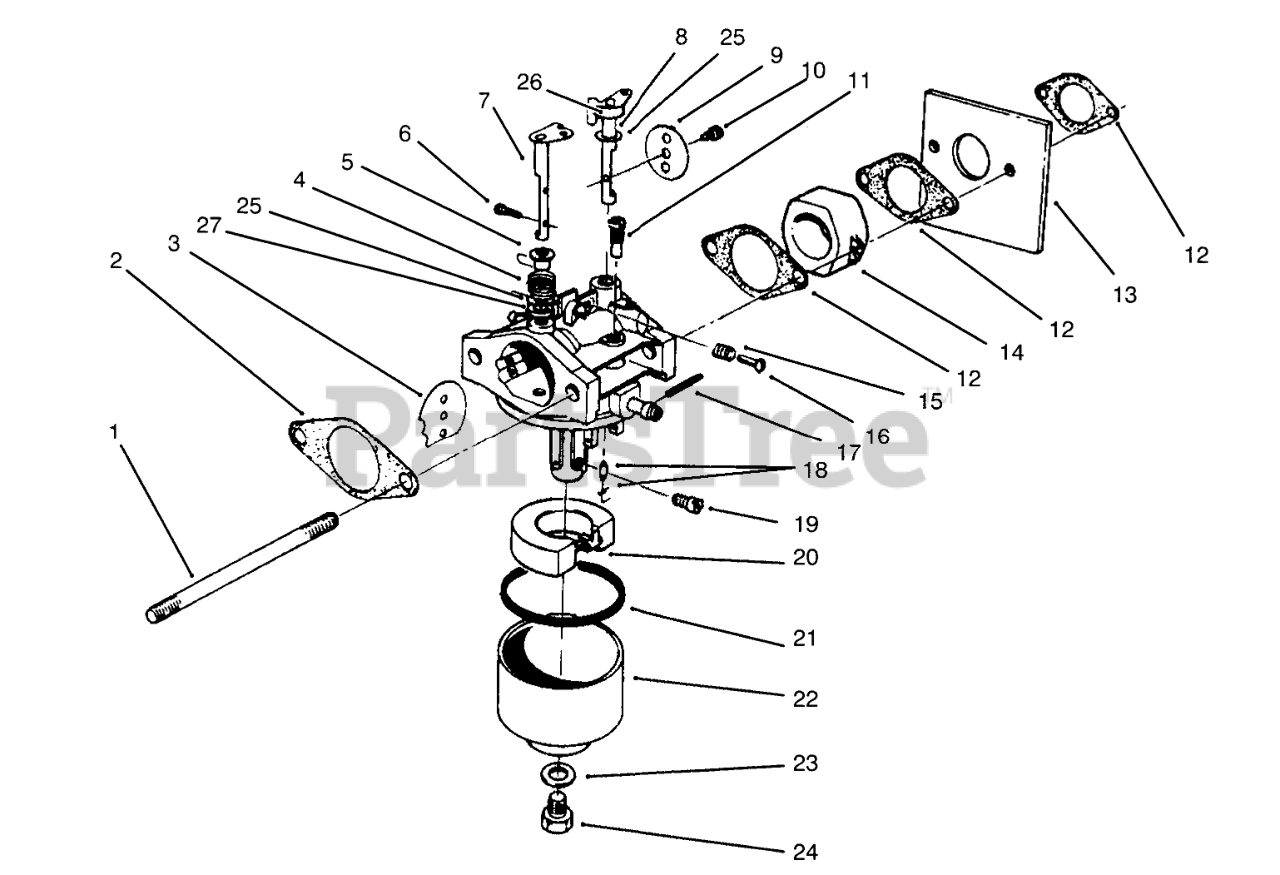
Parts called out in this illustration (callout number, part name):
1	STUD-CARBURETOR
2	GASKET-AIR CLEANER
3	PLATE
4	SPRING
5	BUSHING
6	SCREW
7	SHAFT-CHOKE
8	SHAFT
9	PLATE
10	Screw-Throttle
11	PILOT JET
12	GASKET-CARB
13	SHIELD-CARBURETOR
14	INSULATOR-CARBURETOR
15	SPRING-PILOT SCREW
16	SCREW
17	PIN-HINGE
18	NEEDLE
19	JET-MAIN
20	FLOAT
21	GASKET
22	BOWL - FLOAT
23	GASKET
24	SCREW
27	PACKING
